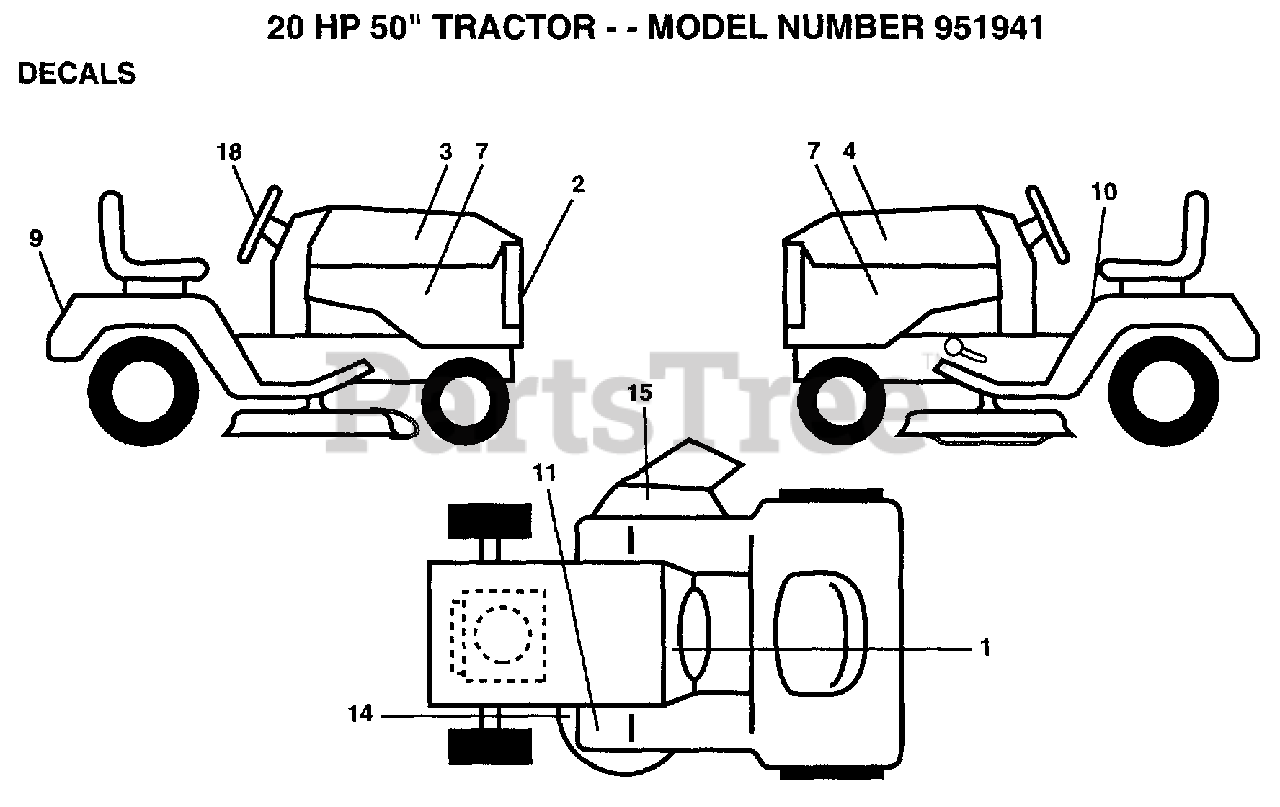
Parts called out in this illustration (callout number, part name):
1	DECAL.DASH.INST.
2	DECAL.GRILL.YARDP
4	DECAL HOOD LH
7	DECAL.PANEL.SIDE
10	DECAL
14	"DECAL.V.BELT.44"""
15	"DECAL, WARNING"
18	DECAL.INS.WHL.STG
